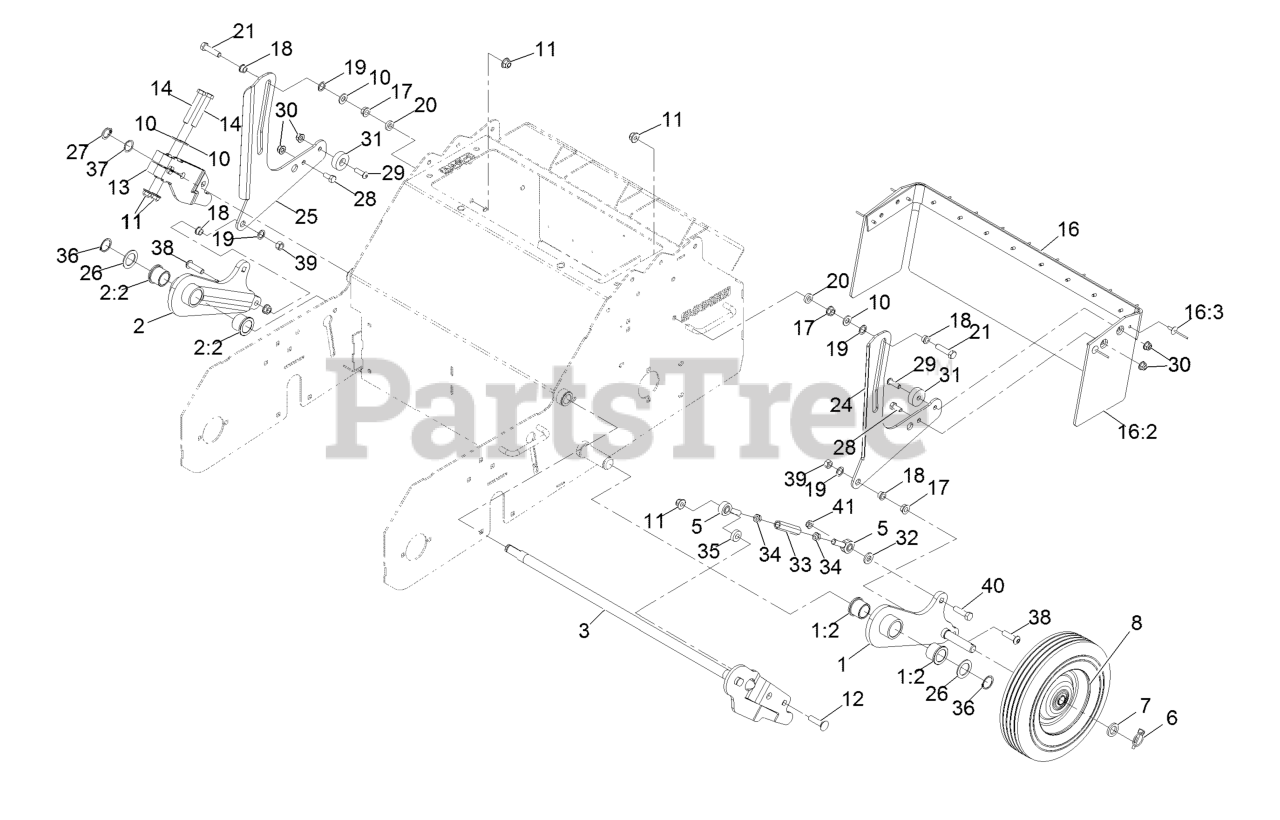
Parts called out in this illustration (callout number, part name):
1	LH Wheel Arm ASM
1:2	Bushing-Flange
2	RH Wheel Arm ASM
2:2	Bushing-Flange
3	Pivot Shaft ASM
5	Balljoint
6	Pin-Klik
7	Spacer-Bearing
8	Wheel, Transport
10	Washer-3/8 SAE
11	Nut-Nyloc 3/8-16 Flg
12	Bolt-Carriage 3/8-16 X 1 1/2
13	Arm-Lift RH
14	Screw-HH 3/8-16 X 2 1/2
16	Guard-Foot
16:2	Foot-Shield
16:3	Rivet-Pop
17	Nut-Whizlock 3/8-16
18	Bushing-Flanged
19	Washer-Nylon
21	Screw-HH 3/8-16 X 1 1/2
24	Guard-Arm, LH
25	Guard-Arm, RH
27	Ring-Retaining
28	Screw-HH 5/16-18 X 3/4
29	Screw-Hsph 5/16-18 X 1
30	Nut-Nyloc 5/16-18 Flg
31	Guide-Arm, Trail
33	Rod-Lift Link
34	Nut-Jam 3/8-24
35	Spacer
36	Ring-Retaining
37	Washer-Wave
38	Screw-HSBH
39	Nut-Hex
40	Screw-HH 3/8-16 X 1 3/8
41	Nut-Nyloc 3/8-16 Thin
